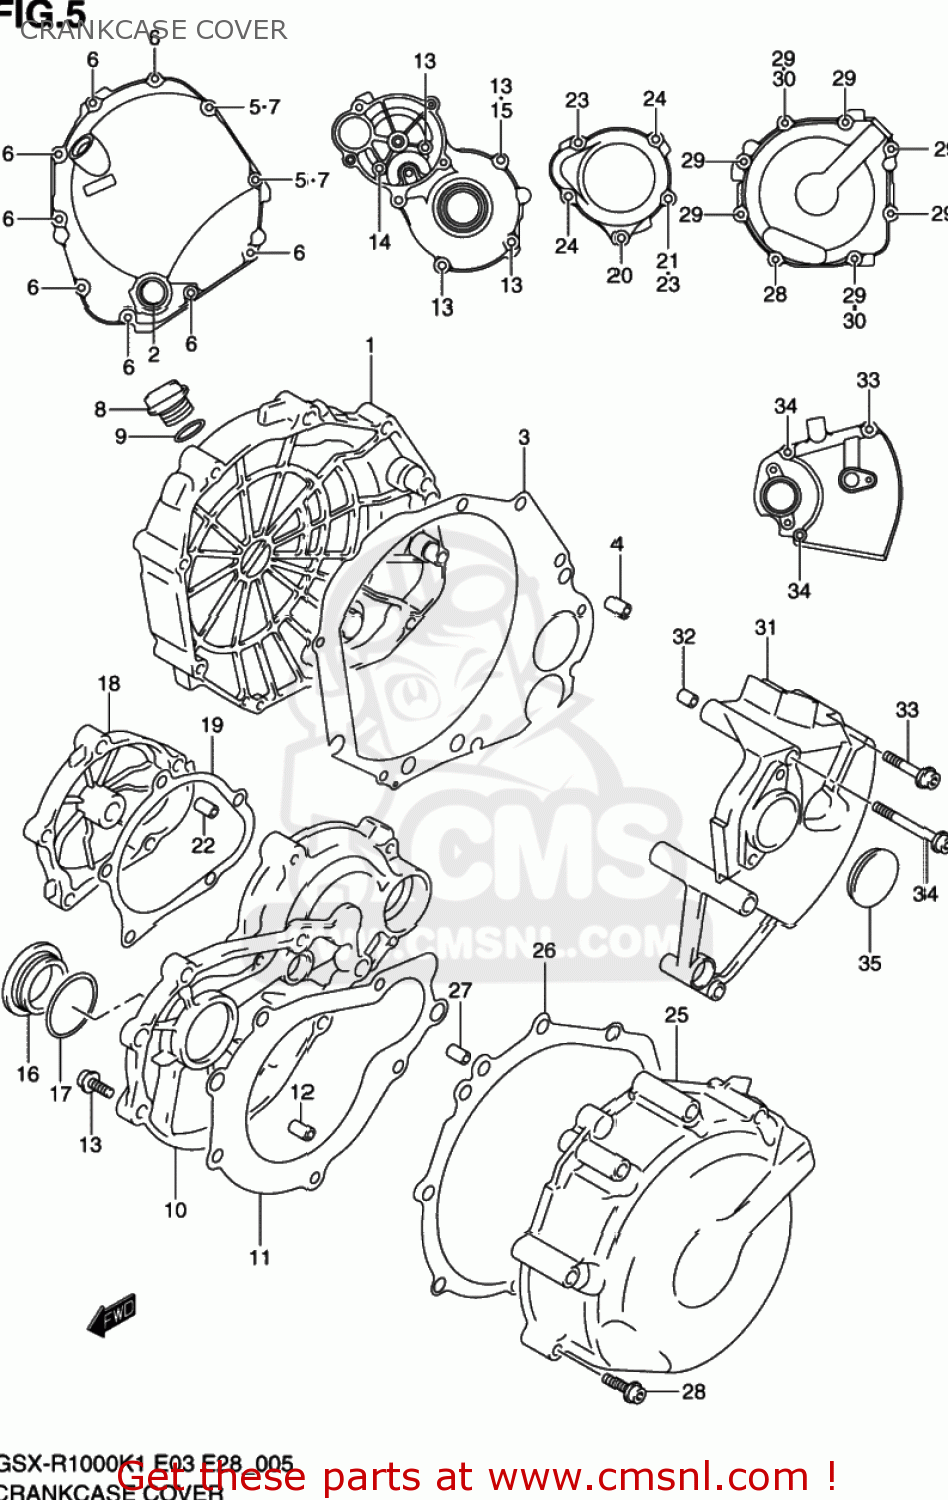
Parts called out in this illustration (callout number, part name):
1	COVER,CLUTCH
2	LENS,OIL LEVEL CHECK
3	GASKET,CL COVE (NAS)
4	PIN
5	GASKET(5.8X13X1.2) (NAS)
6	BOLT
7	BOLT
8	PLUG,OIL FILLER
9	O RING(D:3.1,ID:16.8)
10	COVER,STARTER CLUTCH
11	GASKET,STARTER CLUTCH COVER
12	PIN
13	BOLT,OIL PAN
14	BOLT
15	GASKET(5.8X13X1.2) (NAS)
16	PLUG
17	O RING(D:3.1,ID:32.7)
18	CAP,STARTER IDLE GEAR
19	GASKET,START IDLE GEAR CAP (NAS)
20	BOLT
21	GASKET(5.8X13X1.2) (NAS)
22	PIN
23	BOLT,OIL PAN
24	BOLT
25	COVER,MAGNETO
26	GASKET,MAGNETO COVER (NAS)
27	PIN
28	BOLT
30	GASKET(5.8X13X1.2) (NAS)
31	COVER,ENG SPRO
32	PIN
33	BOLT
34	BOLT
35	CAP(OD:36)
